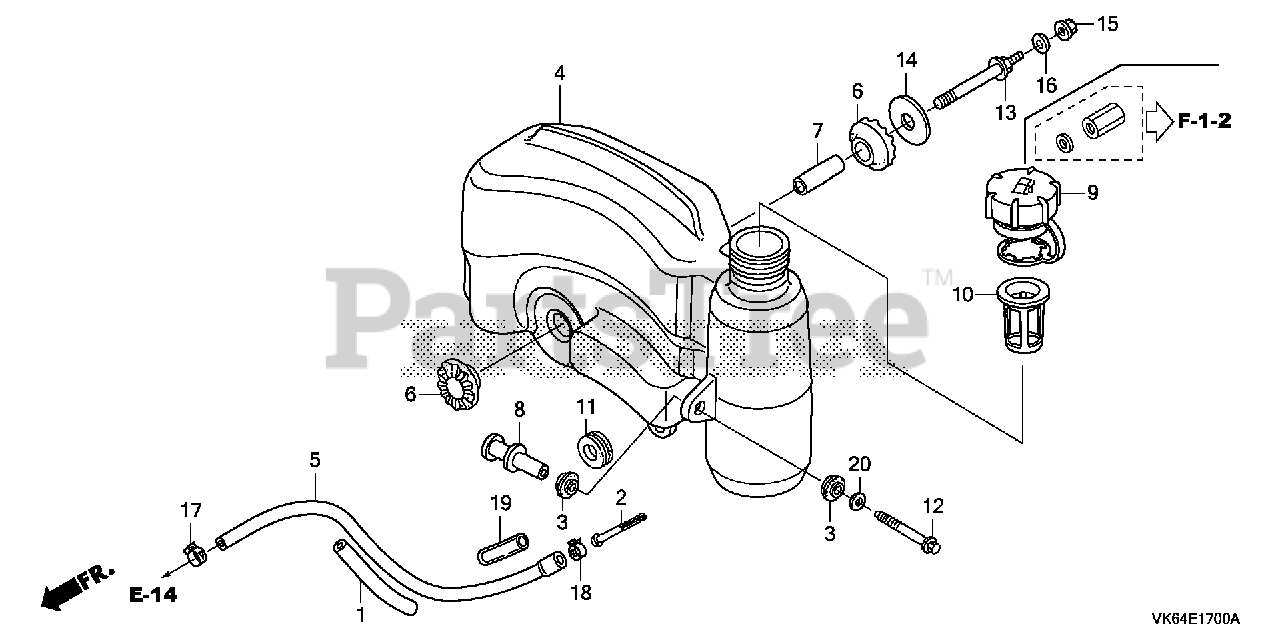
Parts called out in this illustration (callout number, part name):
1	RUBBER, SUPPORTER (107MM)
2	FILTER, FUEL
3	RUBBER, TANK SETTING
4	TANK, FUEL (COO)
4	TANK, FUEL
5	TUBE, FUEL (FKM)
6	RUBBER B, TANK MOUNTING
7	COLLAR, TANK SET
8	COLLAR, TANK
9	CAP ASSY., FUEL TANK
10	GAUGE, FUEL LEVEL
11	CUSHION, RR. FENDER
12	BOLT, FLANGE (6X47) (CT200)
13	BOLT, TANK STAY
14	WASHER, TANK MOUNTING
15	NUT, FLANGE (6MM)
16	WASHER, PLAIN (6MM)
17	CLAMP, TUBE (D8)
18	CLAMP, TUBE (D10.5)
19	BULK HOSE, VINYL (9X11X3000) (9X11X30)
20	WASHER, PLAIN (6MM)
